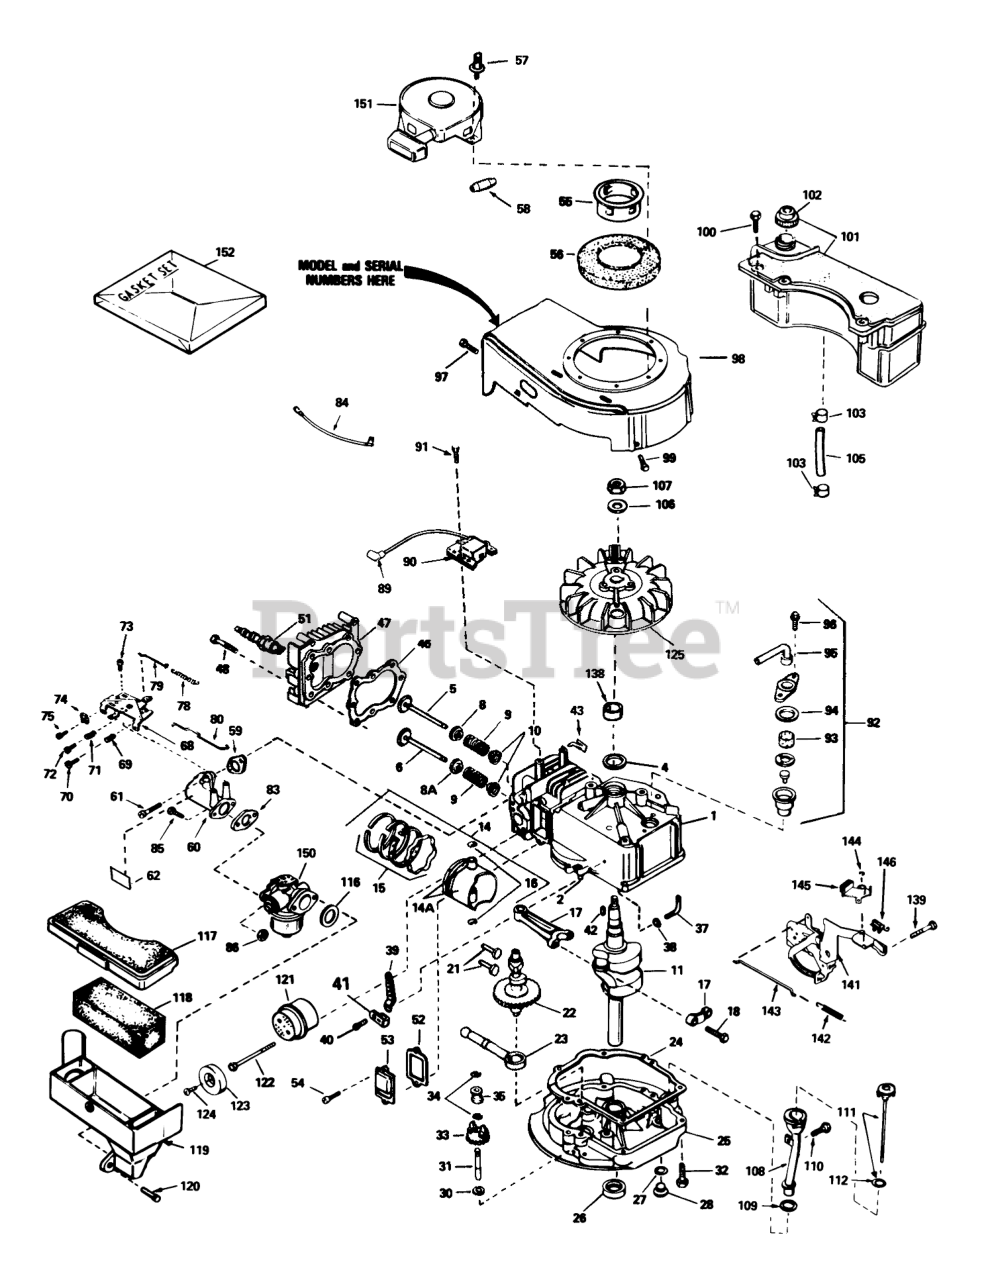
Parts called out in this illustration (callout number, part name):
1	Cylinder Assembly (Incl. Ref. #2 & 4)
2	Pin-Dowel
4	Seal-Oil
5	Valve-Intake (Std.)(Incl. Ref. #10)
5	Valve-Intake (1/32" oversize)(Incl. Ref. #10)
6	Valve-Exhaust (Std.)(Incl. Ref. #10)
6	Valve-Intake (1/32" oversize)
8	Seal Assy., Intake
8A	Cap-Upper Valve Spring
9	Spring-Valve
10	Cap-Valve, Spring
11	Crankshaft
14	Piston-Pin & Ring Assy. (Std.)(Incl. Ref. #14A, 15 & 16)
14	Piston-Pin & Ring Assembly (.010 oversize)(Incl. Ref. #14A, 15 & 16)
14	Piston-Pin & Ring Assembly (.020 oversize)(Incl. Ref. #14A, 15 & 16)
14A	Piston & Pin Assembly (Std.)(Incl. Ref. #16)
14A	Piston & Pin Assembly (.010 oversize)(Incl. Ref. #16)
14A	Piston & Pin Assembly (.020 oversize)(Incl. Ref. #16)
15	Ring Set (Std.)
15	Ring Set (.020" OS)
15	Ring Set (.010" OS)
16	Ring-Retaining, Piston Pin
17	Rod Assembly-Connecting (Incl. Ref. #18)
18	Bolt-Rod, Connecting
21	Lifter-Valve
22	Camshaft(Mech.Comp. Release)
23	Oil Pump ASM
24	Gasket
25	Flange Assembly-Mounting (Incl. Ref. #26, 27, 28 & 31)
26	Seal Oil
27	Gasket-Oil Drain
28	Plug Oil Drain
30	Washer-Flat
31	Shaft-Governor
32	Screw (1/4-20 x 1-1/4)
33	Gear Assembly-Governor (Incl. Ref. #30)
34	Ring-Retaining
35	Spool-Governor
37	Rod-Governor (Incl. Ref. #38)
38	Washer-Flat
39	Governor Lever
40	Screw
41	Clamp-Lever, Governor
42	Key-Flywheel
43	Clip-Wire
46	63573 GIL 42 SNWTHW
47	Head-Cylinder
48	Screw (5/16-18x1-1/2)
51	Plug, Spark (Autolite 458, Champion J-19LM or equiv.)
52	Gasket-Breather
53	Cover-Valve
55	Cup-Starter
56	Screen-Starter
57	Pop Rivet (Can be purchased locally)
58	Retainer-Starter Rope
59	Gasket-Intake
60	Pipe-Intake (Incl. Ref. #59j
61	Screw (1/4-20 x 1)
62	Decal-Primer
68	Control Assy.-Remote Speed (Incl. Ref. #69 thru 72)
69	61709/GIL1515A/95-5
70	Screw
71	Spring-Compression
72	Screw
73	Screw (10-24 x 9/16)
74	Conduit
75	Screw (10-32 x 3/8)
78	Spring Governor
79	2035A67 ADD.ASSEMBL
80	Link-Throttle
83	Gasket
84	Ground Wire
85	Screw (1/4-28 x 7/8)
86	Nut and Lock Washer (1/4-28)
89	Cover-Spark Plug
90	Solid State
91	Screw
92	Breather Assembly (Incl. Ref. #93 thru 96)
93	Element-Breather
94	Gasket-Breather
95	Tube, Breaker
96	Screw (10-24 x 9/16)
97	Screw (10-24 x 9/16)
98	Housing-Blower
99	Screw (1/4-20 x 1/2)
100	Screw (10-32 x 35/64)
101	Tank Assembly-Fuel (Incl. Ref. #102)
102	Cap-Fuel
103	Clamp-Line, Fuel
105	Line-Fuel
106	Washer-Belleville
107	Nut-Flywheel
108	Tube-Oil Fill
110	Screw (10-32 x 1/2)
111	Dipstick-Oil (Incl. Ref. #112)
116	Gasket-Cleaner, Air
117	Cover Air Cleaner
118	Filter-Air Cleaner
119	Body Air cleaner
121	Muffler (Incl. Ref. #122)
123	Cover-Muffler
124	Screw
125	Flywheel
139	Screw (1/4-20 x 3/8)
141	Bracket Assy.
142	Spring-Extension
143	Link-Control
144	Ring-Retaining
145	Lever-Brake
146	Terminal
150	Carburetor (Inc. Ref. #83)
151	tarter-Rewind
152	Gasket Set (Incl. Items Marked )
